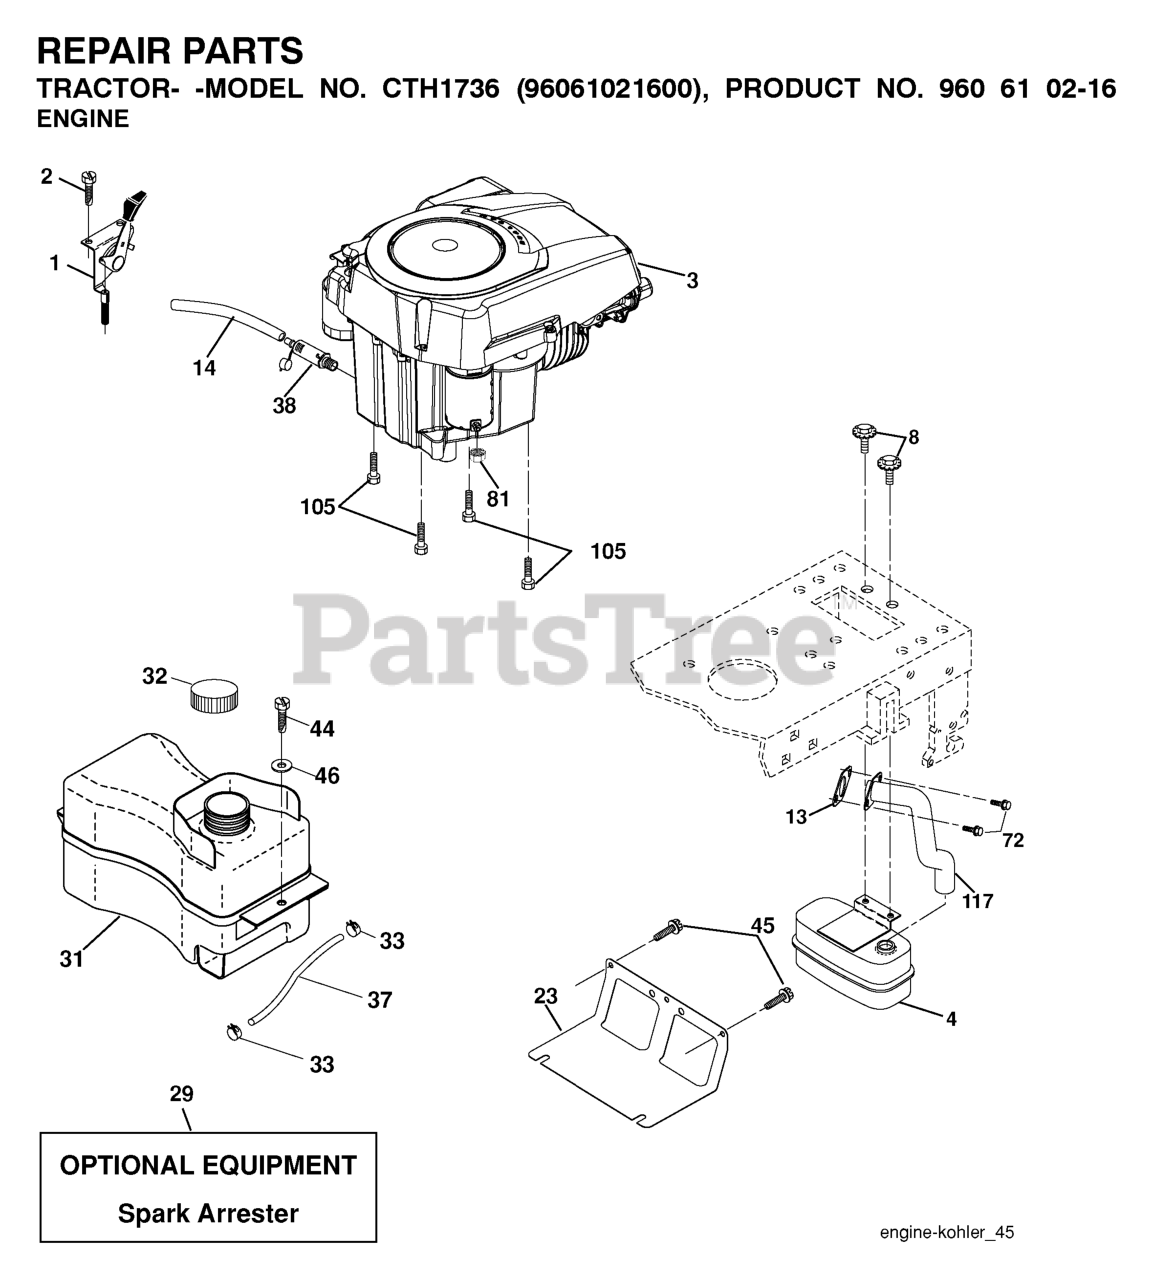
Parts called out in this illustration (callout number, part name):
1	CONTROL.TH/CK.C.
2	SCREW
4	MUFFLER.SINGLE.CYL.KOHL/B&S
8	BOLT.5/16-18UNCX3/4 W/SEMS.BLK
13	GASKET.EXHAUST.KOHLER
14	TUBE, DRAIN OIL ASM.
23	SHIELD.BROWNING.DBR.GUARD
29	KIT.SPARK ARRESTOR 794945 B&S
31	RP TANK FUEL FRT 1.5 GAL
32	FUEL CAP
33	HOSE CLAMP
37	LINE.FUEL.20
38	PLUG DRAIN OIL EASY
44	SCREW HEXWSHR 1/4-20X3/4
45	SCREW, 3/8-16X3/4
72	SCREW.SOCKET HD.5/16-1
81	NUT
105	SCREW 3/8-16X1
116	NUT.HEX.FLANGE.TOPLOCK
117	RP.TUBE.EXHAUST.KOHL.COURAGE
